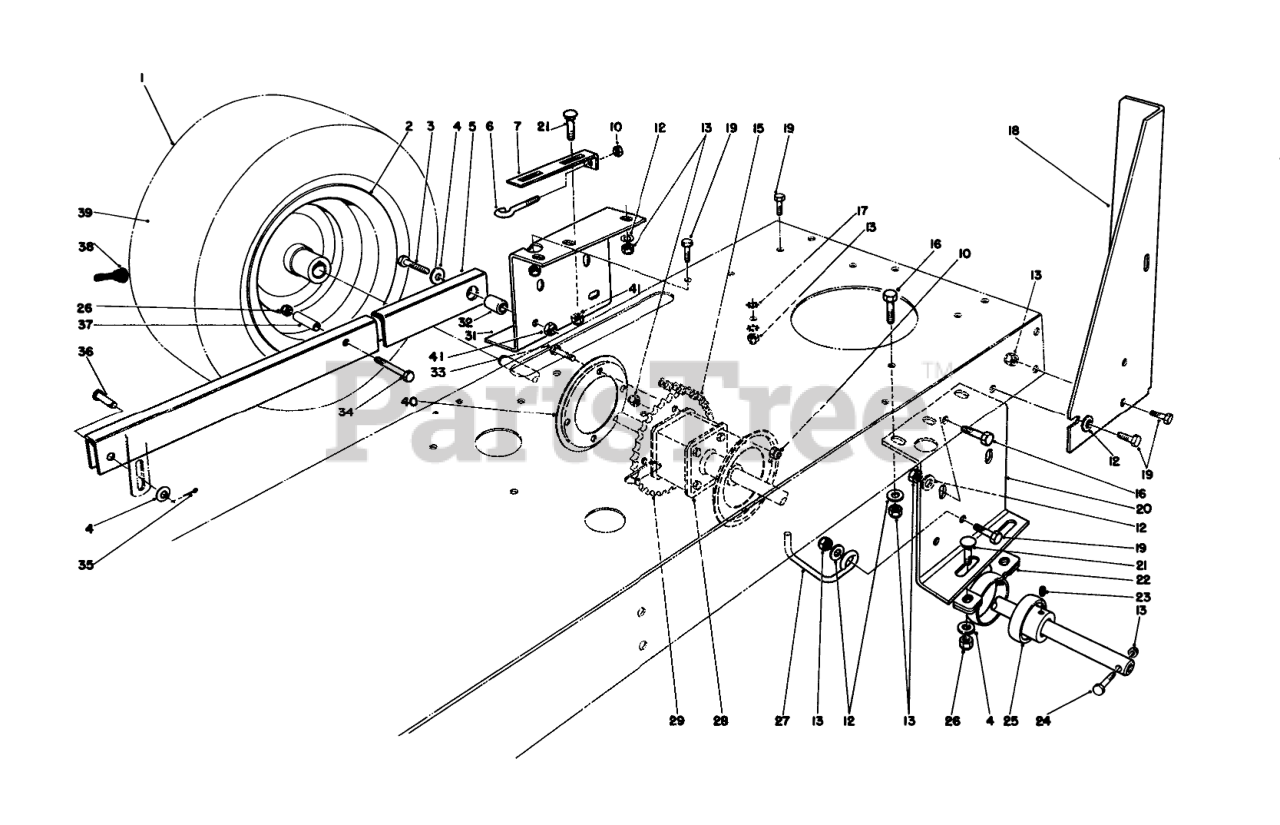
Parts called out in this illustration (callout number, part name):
3	SCREW-HH
4	WASHER-FLAT
5	Arm-Suspension R.H.
6	SCREW-ADJUSTING
7	PLATE-ADJUSTING
10	NUT-HEX
12	WASHER-PLAIN
13	NUT-LOCK, NI
15	ROLLER CHAIN
16	SCREW-HH
17	WASHER-LOCK, INTERNAL
18	LH STANDBAR B
19	SCREW-HH
20	LH REAR AXLE SUPT R
21	BOLT-CARR
22	RTNR-PILLOW BLK
23	SCREW-SET, HSH
24	AXLE MTG BOLT
25	Bearing-Ball (Incl. Ref. #23)
26	NUT-LOCK, NI
27	BELT GUIDE
28	DIFFERENTIAL
29	SPROCKET
31	RH AXLE SUPPORT R
32	PIN-SUPT ARM
33	SCREW-HH
34	SCREW-HH
35	PIN-COTTER
36	PIN-CLEVIS
37	SPACER-SPLIT TUBE
38	STEM-VALVE
39	TUBE-INNER
40	Guide-Chain
41	NUT-LOCK, NI
